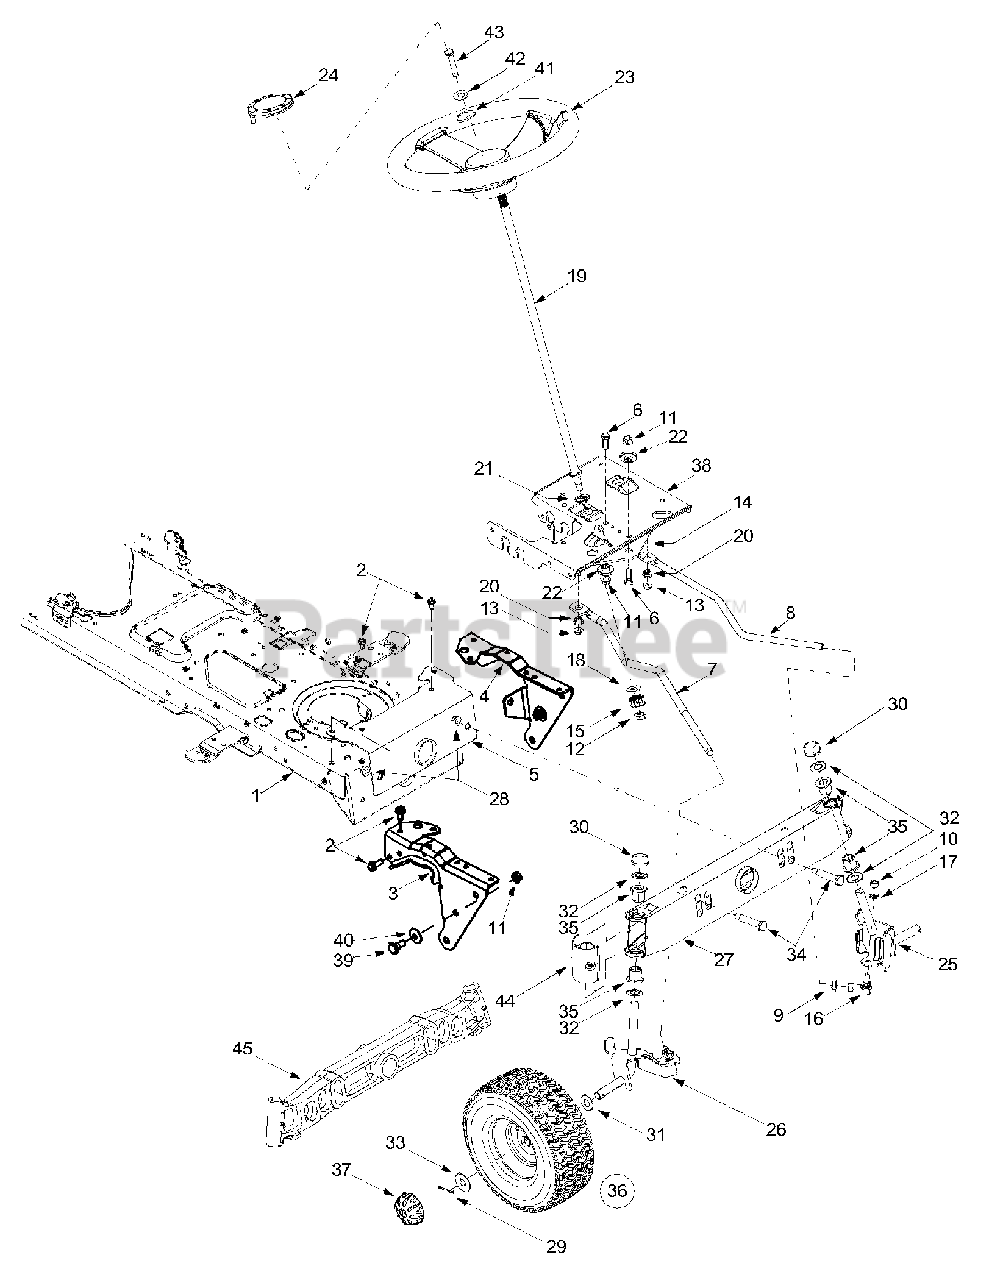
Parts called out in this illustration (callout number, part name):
6	Hex Cap Screw, 3/8-16 x 1 (Grade 5)
7	RH Drag Link
8	LH Drag Link
9	Jam Nut, 7/16-20 (Grade 2)
10	Hex Nut, 3/8-24 (Grade 2)
11	Flange Lock Nut, 3/8-16
12	Flange Lock Nut, 7/16-20
13	Flange Lock Nut, 5/16-18
14	Steering Gear, 11/90 Ratio
15	Steering Pinion Gear
16	Ball Joint, 7/16-20
17	Lock Washer, 3/8
18	Flat Washer, .51 x 1.12 x .06
19	Steering Shaft, .625 OD x 24.4
20	Plastic Bushing, .38 ID
21	Hex Flange Bearing, 5/8
22	Shoulder Spacer, .38 ID
23	Steering Wheel
24	Steering Wheel Cap, w/ Icon
25	LH Axle Assembly, .625 Diameter
26	RH Axle Assembly, .625 Diameter
28	Flange Lock Nut, 3/8-16
29	Cotter Pin
30	Push Cap, .625 Dia.
30	Push Cap, .750 Dia.
31	Flat Washer, .64 x 1.0 x .12
32	Flat Washer, .64 x 1.24 x .06
32	Flat Washer, .78 x 1.589 x .06
33	Flat Washer, .635 x 1.589 x .06
34	Shoulder Screw, .5 x 2.2, 3/8-16
35	Flange Bearing, .632 ID x .937 OD
35	Flange Bearing, .76 ID x .937 OD
37	Hub Cap
39	Shoulder Screw, 3/8-16
40	Bell Washer, .39 x 1.13 x .062
41	Flat Washer
42	Bell Washer, .34 x .872
43	Hex Bolt, 5/16-18 X 1
44	Pivot Bar End Cap
45	Cast Iron Pivot Bar w/ Fittings, .625
45	Cast Iron Pivot Bar w/ Fittings, .750
